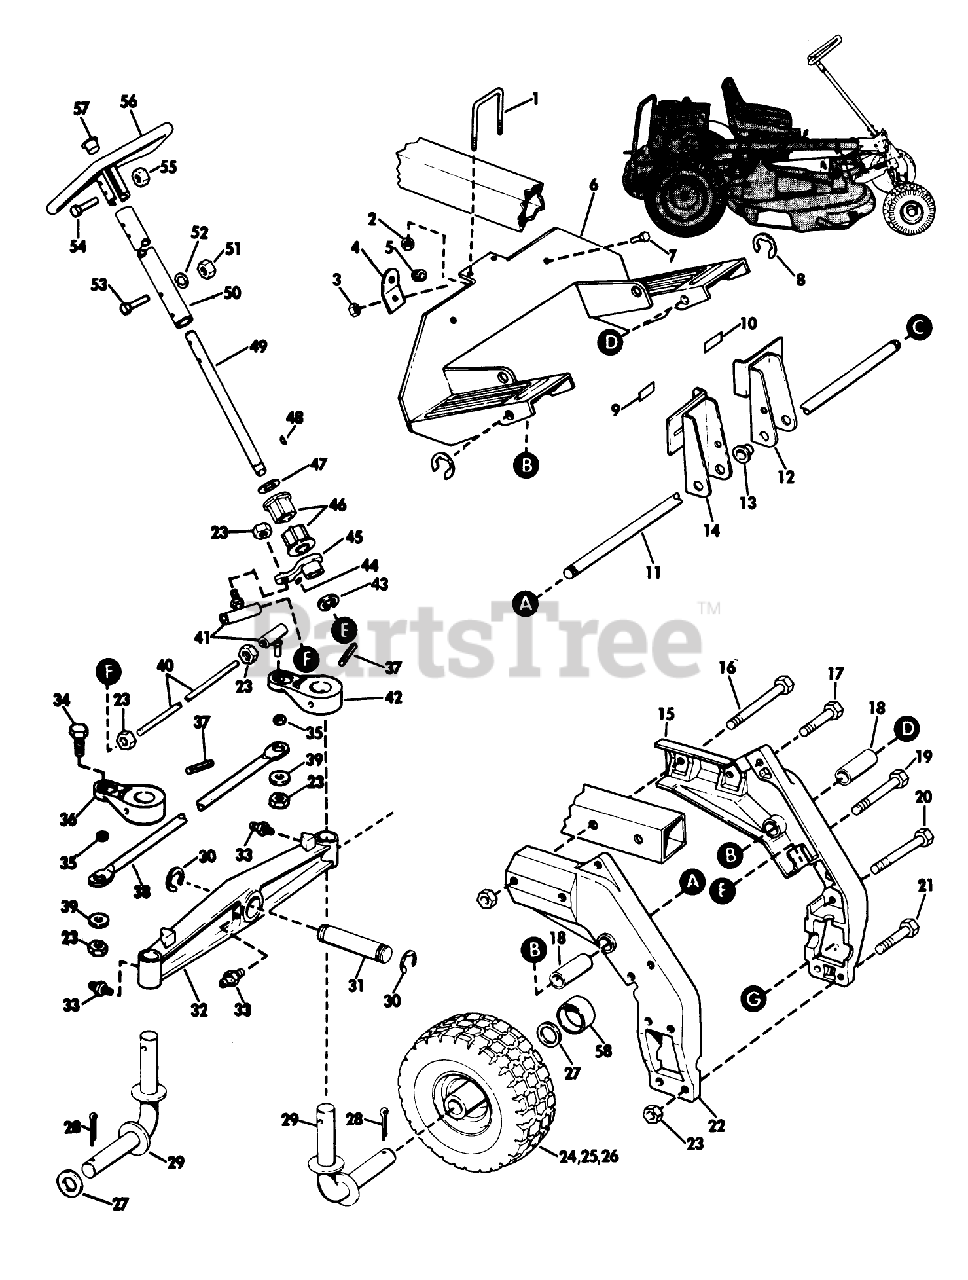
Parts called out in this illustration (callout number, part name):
5	Bushing
33	Grease Fitting
34	Screw-King Pin
55	Nut-Steering Shaft
